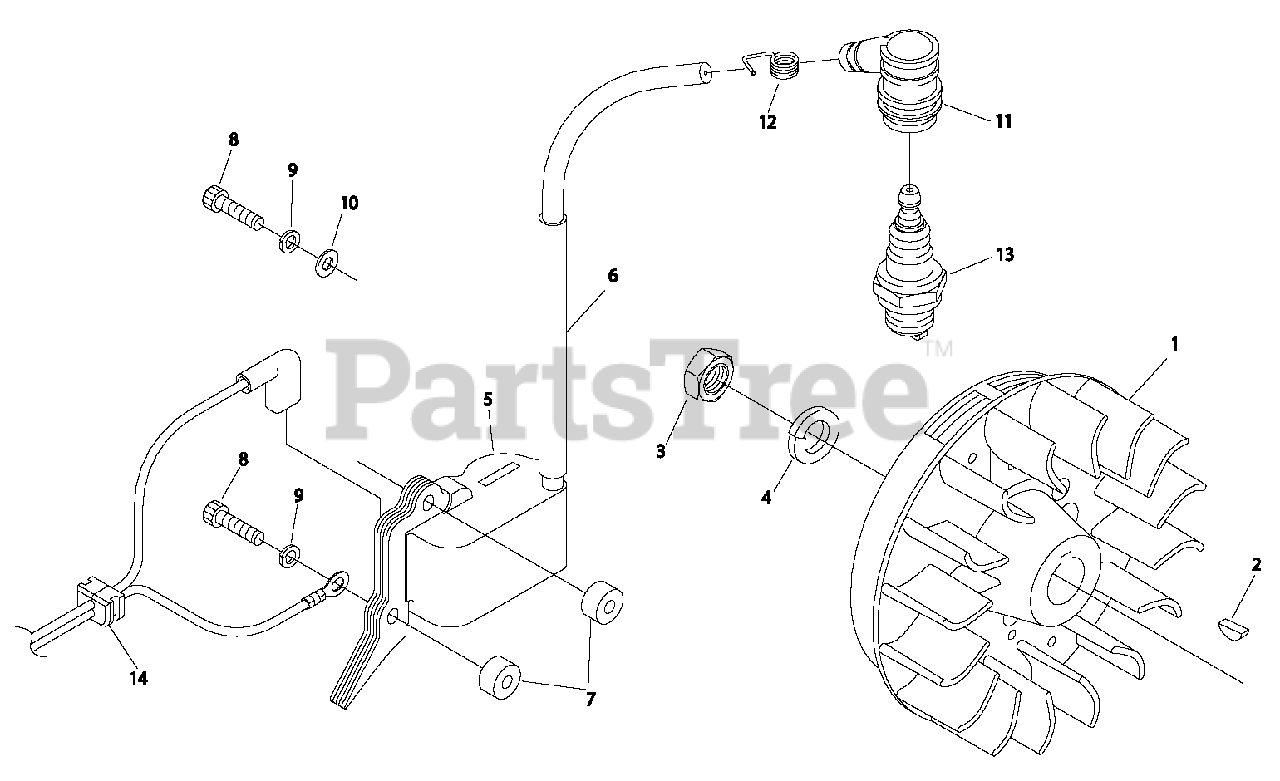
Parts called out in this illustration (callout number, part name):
1	FLYWHEEL
2	KEY, WOODRUFF 3×10
3	NUT 10×1.25
4	WASHER, SPRING 10
5	COIL ASSY, IGNITION
6	TUBE, PROTECTIVE
7	INSULATOR 4.2×11×6
8	BOLT M4×24
9	WASHER, SPRING 4 MM
10	WASHER 4.3×9.6×0.8
11	CAP, SPARK PLUG
12	TERMINAL, SPARK PLUG
13	SPARK PLUG - BMR6A
14	GROMMET
